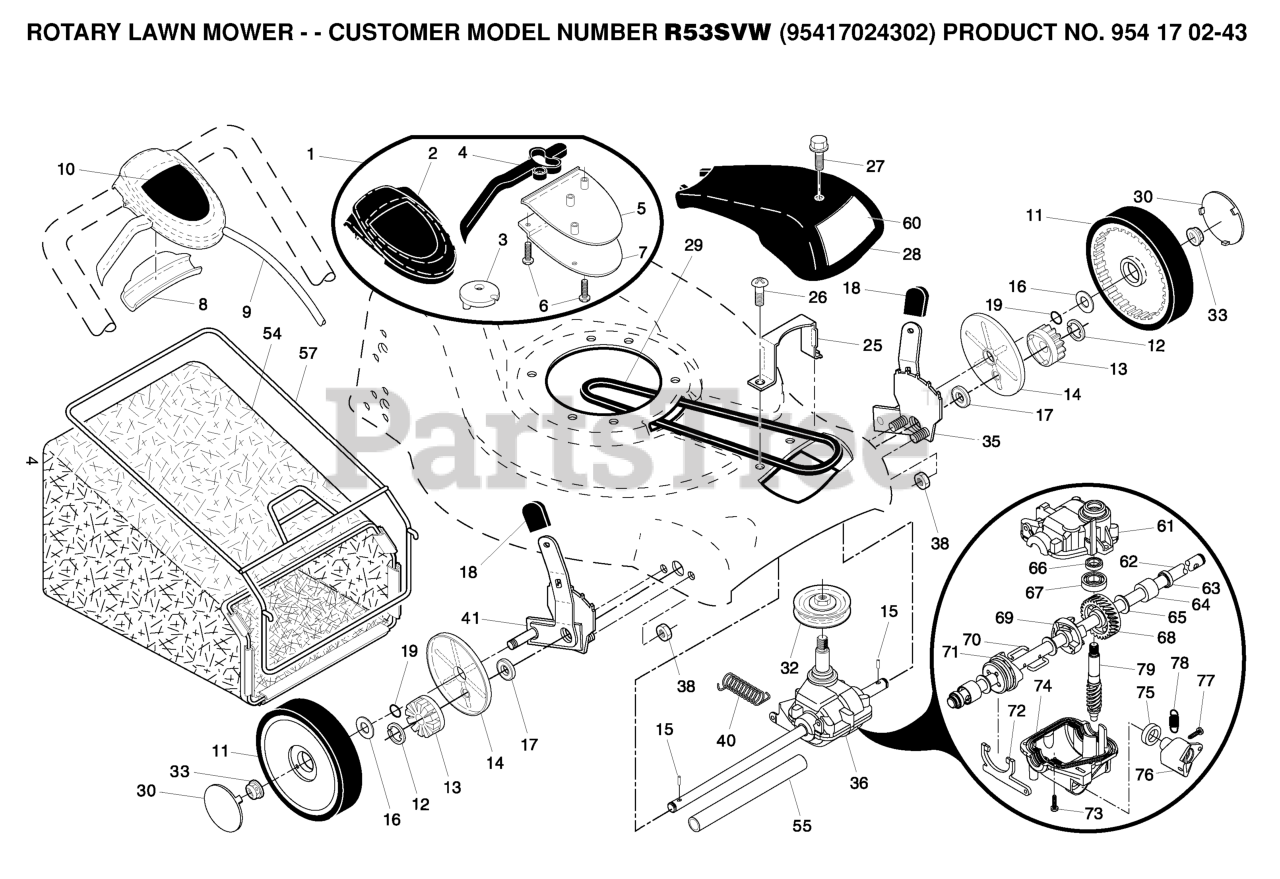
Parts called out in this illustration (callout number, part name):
1	CONTROL.DR.EZ.FWGD.SHORT.GY/BL
2	CASE.TOP.GRAY
3	PULLEY.CAM.DRIVE.CONTROL.HV
4	LEVER, AUTOWALK DRIVE CONTROL
5	CASE BOTTOM
6	SCREW, PHILLIPS HEAD 10 X 5/8
7	BRACKET, DRIVE CONTROL
8	EZ WALK SNAP COVER PLATE
9	CABLE.ASM.
10	DECAL, DRIVE
12	E-RING 7/16 RE
13	PINION
14	COVER.DUST.WHEEL
15	PAWL.DRIVE
16	WASHER FLUT
17	BEARING
18	SELECTOR KNOB
19	O-RING
25	KEEPER.BELT
26	SELF-TAPPING SCREW 5/16-18X3/4
27	SCREW, HEX HD TAPPING #10-24 1
28	COVER.DRIVE.21.FWGD.GRAY
29	BELT.DRIVE.FGD.
30	HUBCAP
32	RP PULLEY.DRIVE.EZ
33	HEX FLANGE LOCKNT
35	RP KIT.ADJUSTER.ASM.EZ
36	TRANSMISSION.21RD
38	LOCKNUT.NYLOC.1/4-20
40	SPRING RETURN
41	KIT.ADJUSTER.AS.EZ RT
55	DRIVESHAFT COVER
57	BAG FRAME
60	DECAL DRIVE COVER
61	GEARCASE.HOUSING
62	SHAFT.OUTPUT
63	SEAL.OUTPUT.SHAFT
66	SEAL INPUT SHAFT
68	GEAR.27.TEETH.WALK.MOWER
70	WIRE, FORMED (15966)
74	GEARCASE.HOUSING.LOWER
77	SCREW.LEVER.
79	SHAFT INPUT (13041)
